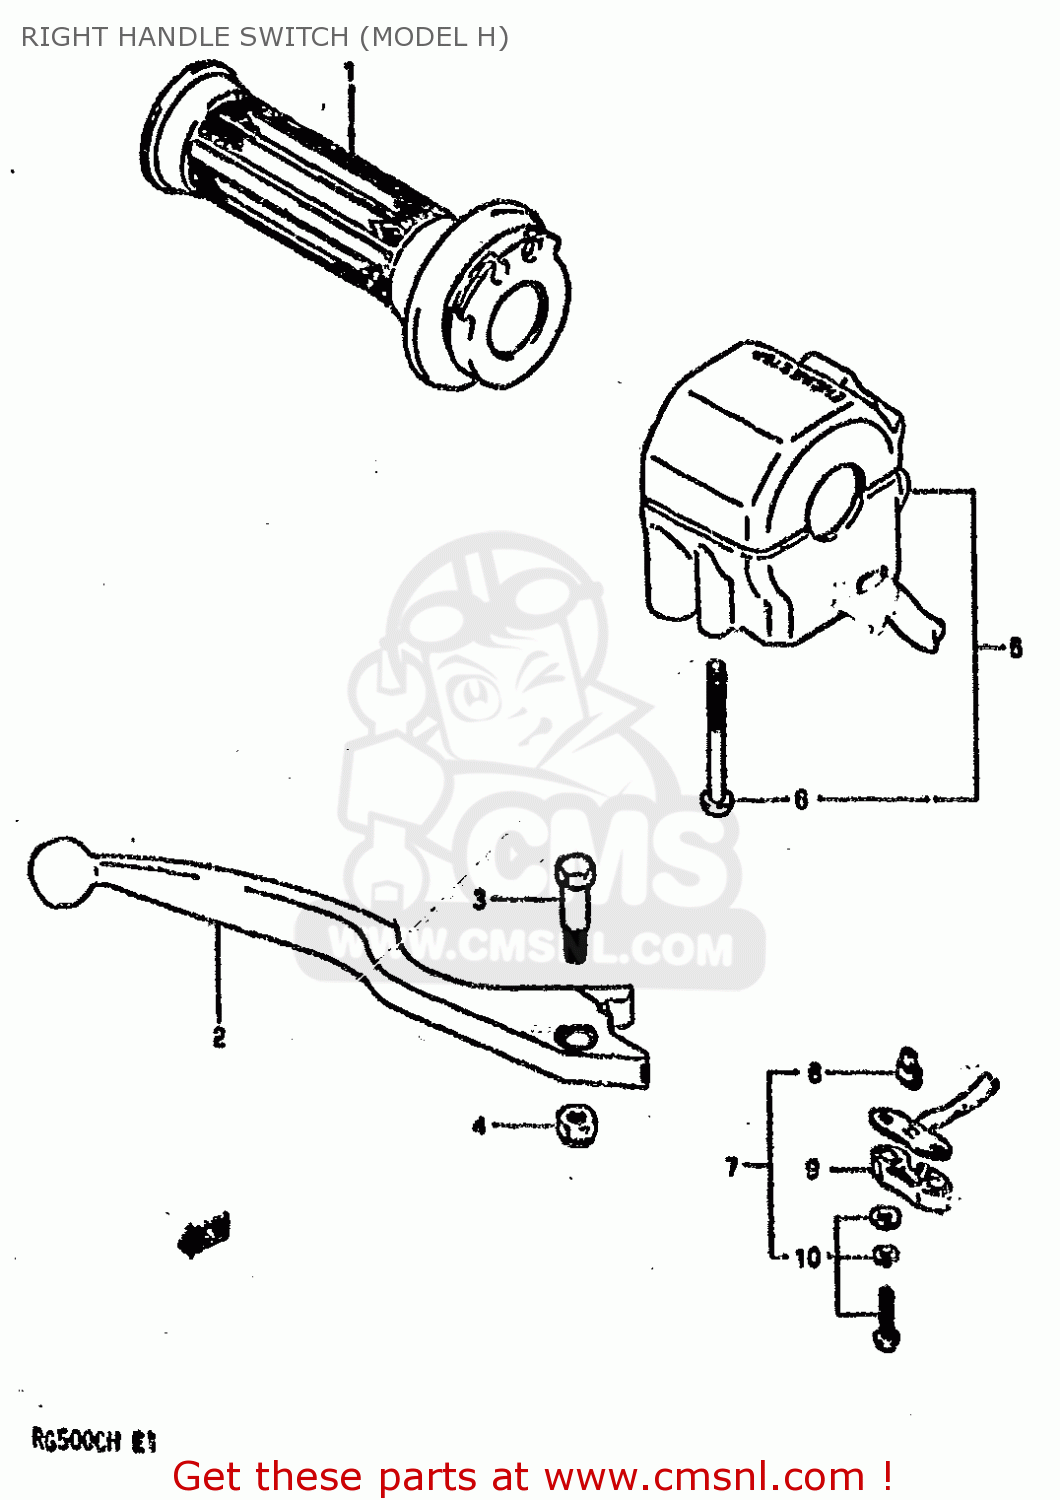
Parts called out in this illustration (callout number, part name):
1	GRIP,THROTTLE
2	LEVER,BRAKE
3	BOLT,LEVER PIVOT
4	NUT
5	SWITCH,HANDLE,
6	SCREW, 5X45
8	SWITCH ASSEMBLY
9	CONTACT,SWITCH
10	COVER,FR BK TERMINAL BASE
11	SCREW
